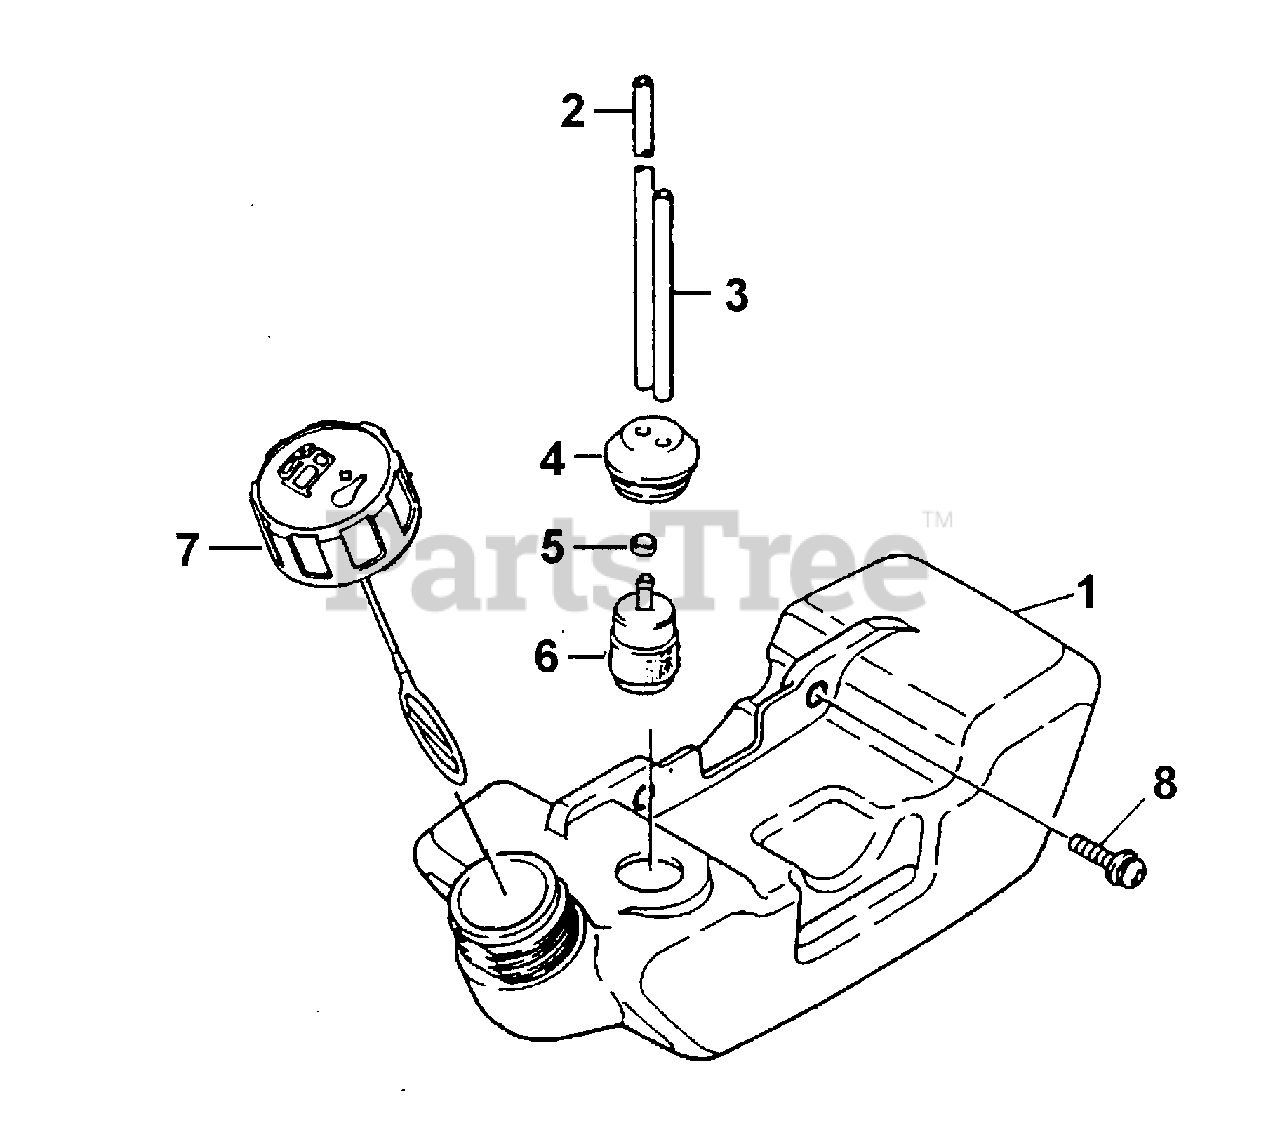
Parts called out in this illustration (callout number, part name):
1	FUEL TANK ASSY.
2	TUBE, FUEL
3	TUBE, FUEL
5	BUSHING
6	FILTER, FUEL
7	TANK CAP ASSY.
8	SCREW & WASHER
